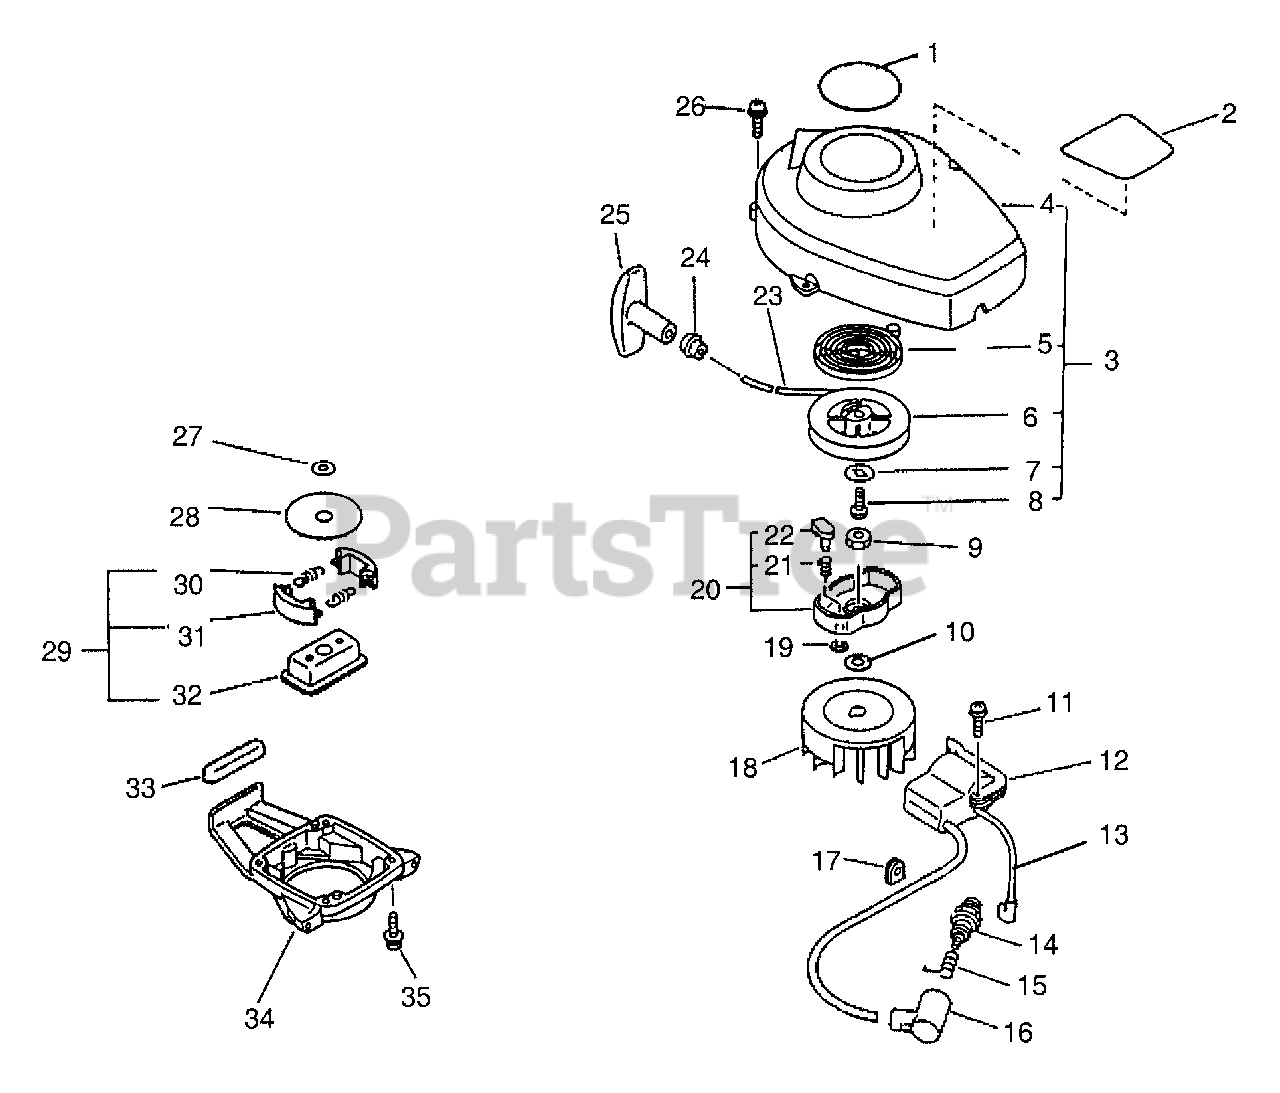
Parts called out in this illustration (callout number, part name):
1	LABEL, HC-1600
2	LABEL, CAUTION
3	STARTER ASSY
4	CASE, STARTER
5	SPRING, RECOIL
6	REEL, ROPE
7	WASHER
8	SCREW
10	WASHER, SPRING 8
11	SCREW 4×22
12	COIL, IGNITION
13	LEAD
14	SPARK PLUG - BPM-7Y
14	SPARK PLUG - BPMR7A
15	TERMINAL, SPARK PLUG
16	CAP, SPARK PLUG
18	FLYWHEEL
19	E-RING 4
20	STARTER PAWL ASSY
21	SPRING, RETURN
22	PAWL, STARTER
23	ROPE, STARTER
24	GUIDE, ROPE
25	GRIP, STARTER
26	BOLT 4×16
27	WASHER, CLUTCH
28	PLATE, CLUTCH
29	CLUTCH ASSY
30	SPRING, CLUTCH
31	SHOE, CLUTCH
32	HUB, CLUTCH
33	CUSHION, FUEL TANK
34	HOUSING, CLUTCH
35	BOLT 4×16
